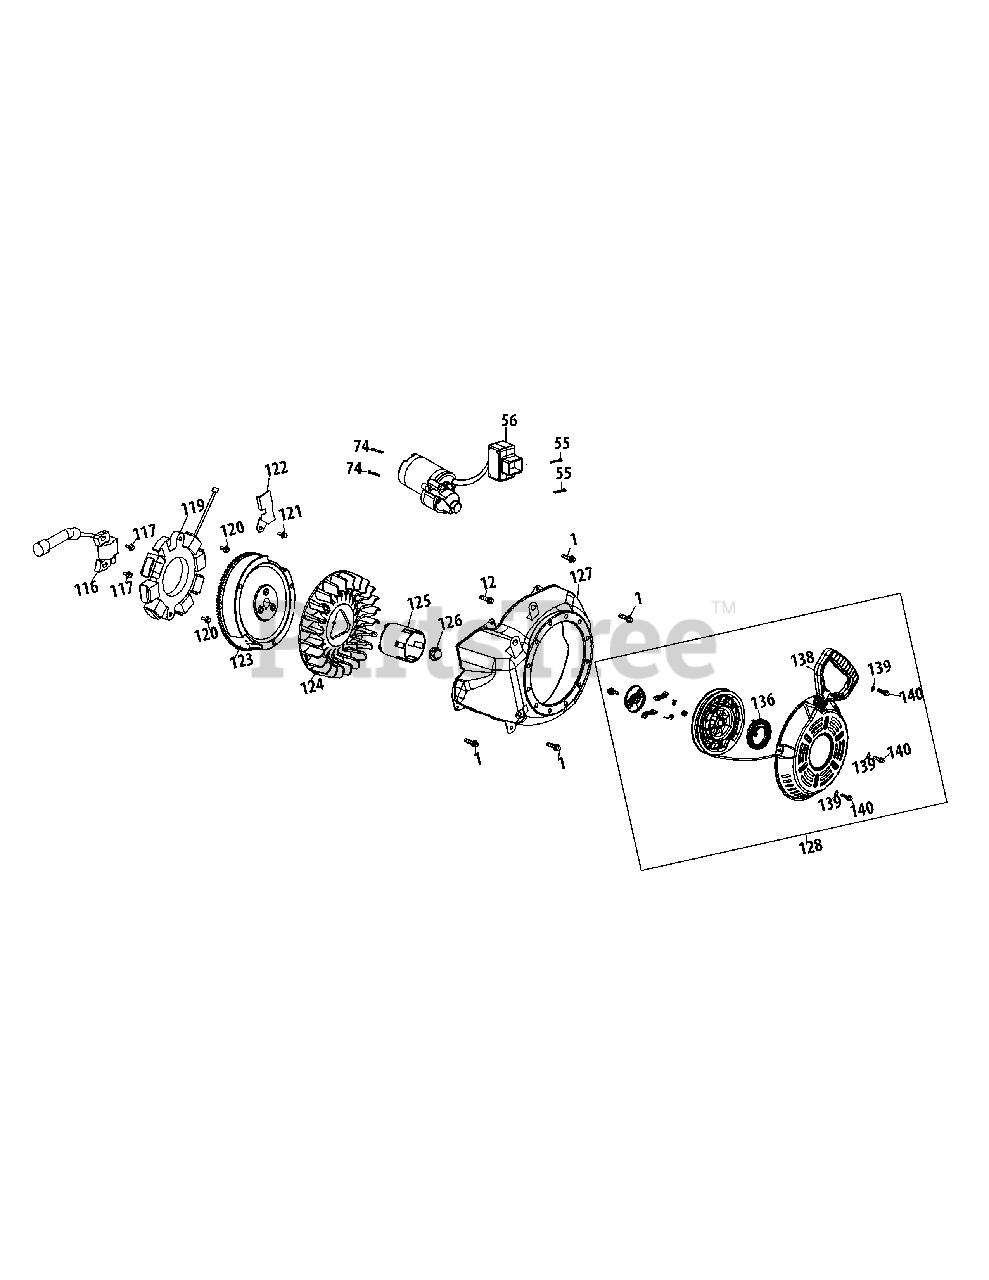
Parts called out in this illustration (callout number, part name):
1	BOLT M6×12
12	BOLT M6×16
55	BOLT M4×55
56	ELECTRIC STARTER
74	BOLT M8×55
116	IGNITION COIL ASSEMBLY
117	IGNITION COIL BOLT
119	ALTERNATOR ASSEMBLY
120	BOLT M6×30
121	BOLT M6×8
122	WIRE PLATE
124	COOLING FAN
125	STARTER CUP
126	NUT, SPECIAL, M16×1.5
127	BLOWER HOUSING
128	RECOIL STARTER
136	RECOIL SPRING
138	STARTER HANDLE
139	GASKET ?6
140	BOLT M6×10
